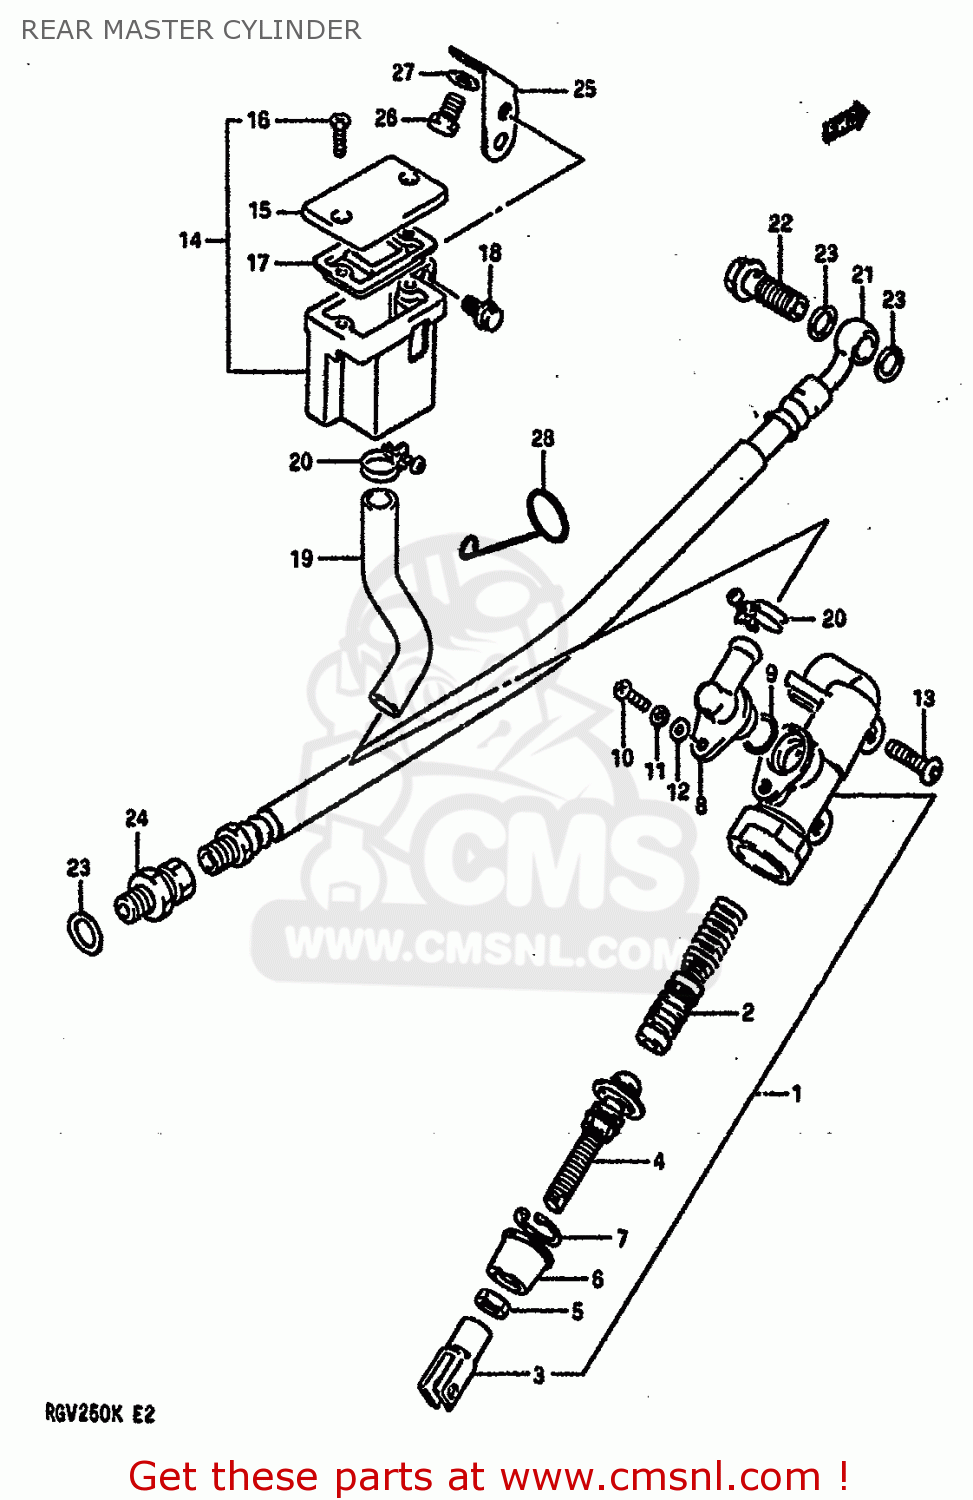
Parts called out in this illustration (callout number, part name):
1	CYLINDER ASSY,REAR MASTER
2	PISTON/CUP SET
3	YOKE
4	ROD,PUSH
5	NUT,MASTER CYLINDER
6	BOOT
7	CIRCLIP
8	CONNECTOR
9	O RING
10	SCREW
11	LOCK WASHER
12	WASHER
13	SCREW(6X16)
14	TANK ASSEMBLY,RESERVOIR
15	CAP
16	SCREW
17	DIAPHRAGM
18	BOLT 6X16
19	HOSE,RESERVOIR TANK
20	CLAMP
21	HOSE,REAR BRAKE
22	BOLT UNION
23	WASHER(10X15X1.5)
24	ADAPTER,BRAKE HOSE
25	PLATE,RESERVOIR TANK
26	BOLT
27	WASHER
28	GUIDE,REAR BRAKE HOSE
